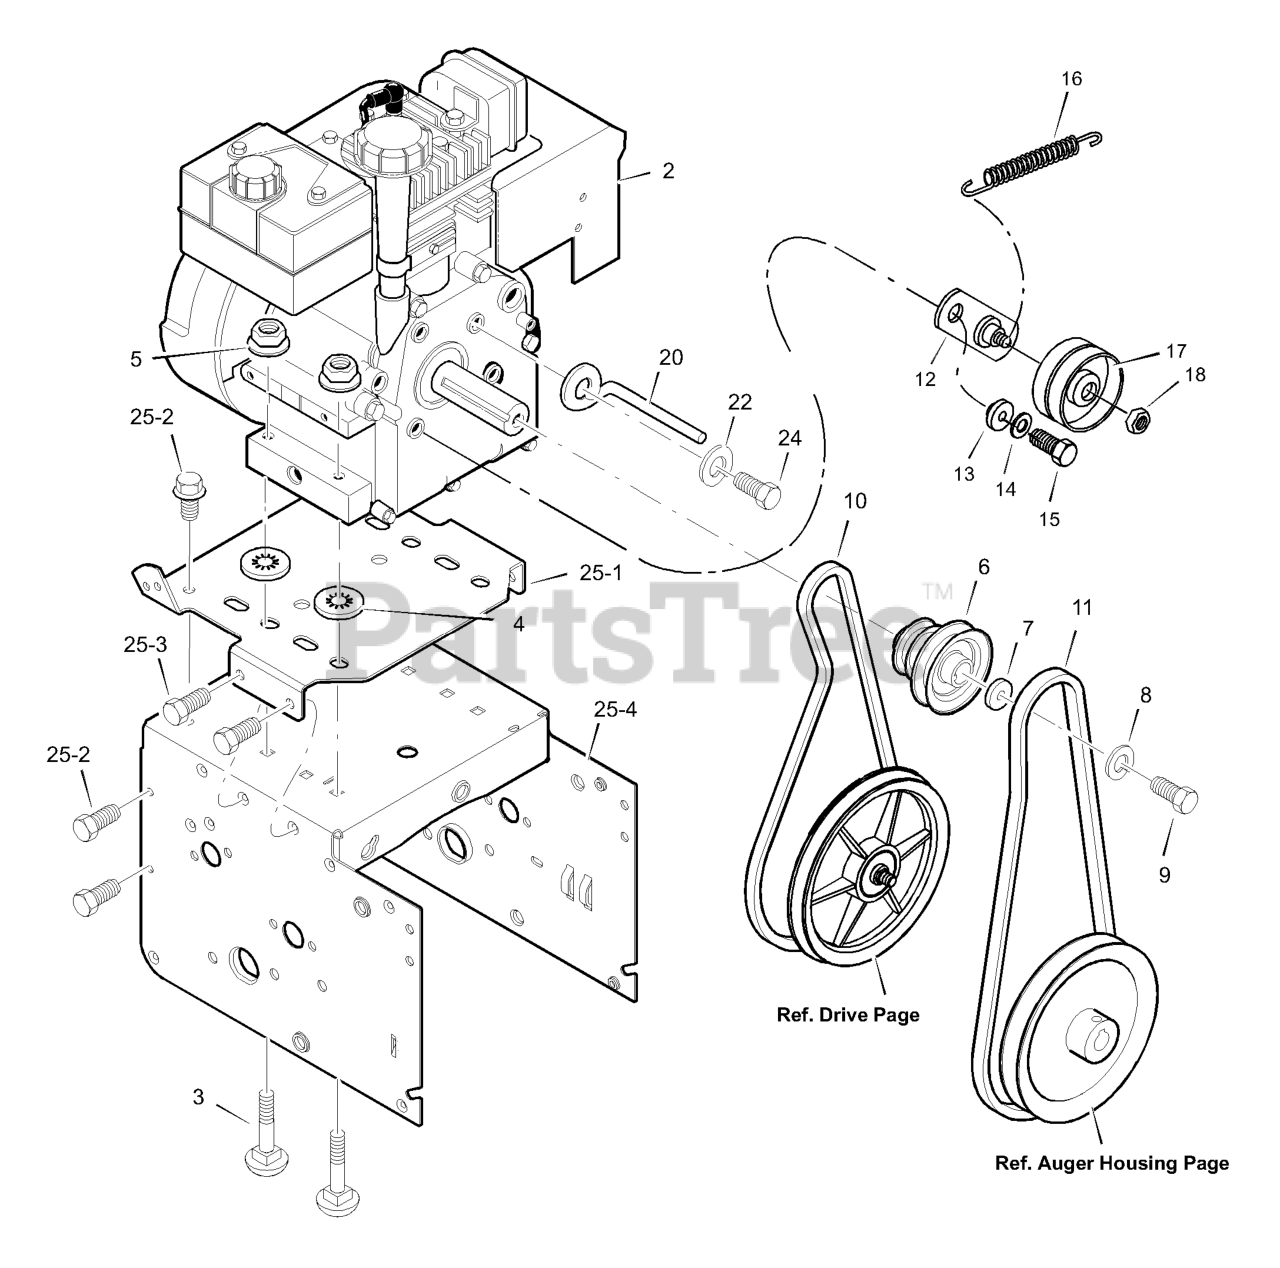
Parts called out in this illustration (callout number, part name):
2	ENGINE
3	BOLT, CARRIAGE 5/16-18
4	RETAINER, PUSH
5	NUT 5/16-18
6	PULLEY, ENGINE
7	WASHER
8	WASHER .38ID
9	SCREW, 3/8-24 x 1.00
10	BELT, DRIVE V3L
11	BELT, AUGER V4L
12	BRACKET ASSEMBLY, IDLER
13	BUSHING, IDLER BRACKET
14	WASHER, SPLIT
15	SCREW 5/16-24 X 0.75
16	SPRING, IDLER TRACTION DRIVE
17	PULLEY, IDLER
18	NUT, JAM 3/8-16
20	GUIDE, BELT
22	WASHER .31X.58X.08
24	SCREW, 5/16-24 x 0.75
25-1	PLATE, ENGINE MOUNT
25-2	SCREW, TAP 1/4-20 X .63
25-3	SCREW, TAP 5/16-18 X .50
25-4	FRAME, MOTOR BOX
